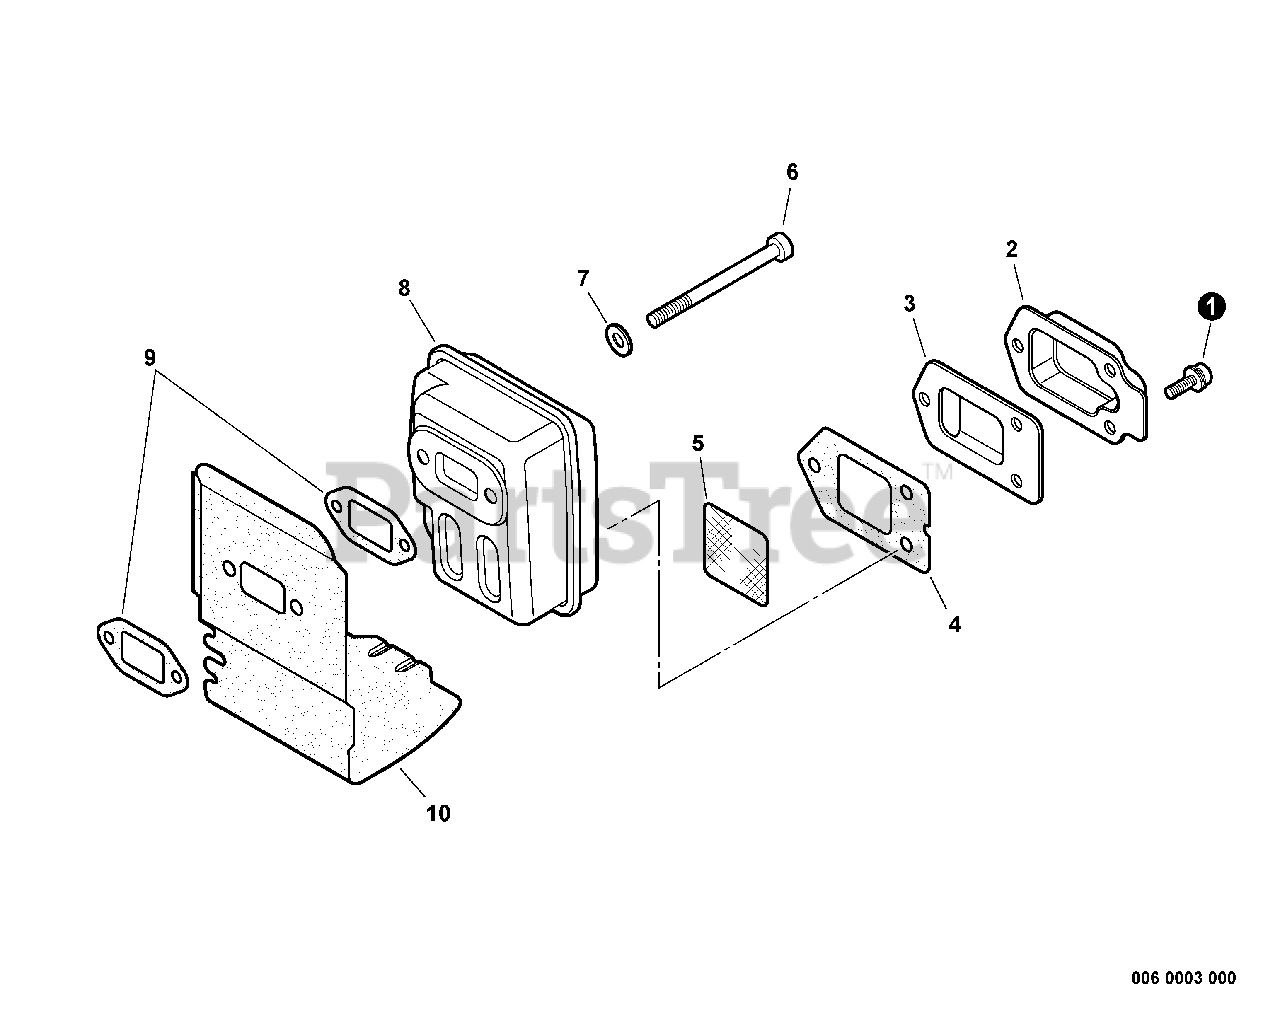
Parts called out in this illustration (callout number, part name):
1	SCREW 4×10
2	GUIDE, EXHAUST - INNER
3	GUIDE, EXHAUST
4	GASKET, EXHAUST
5	SCREEN, SPARK ARRESTER
6	BOLT 5×55
7	WASHER, FLAT 5.5×10×0.8
9	GASKET, EXHAUST
10	HEAT SHIELD, EXHAUST
